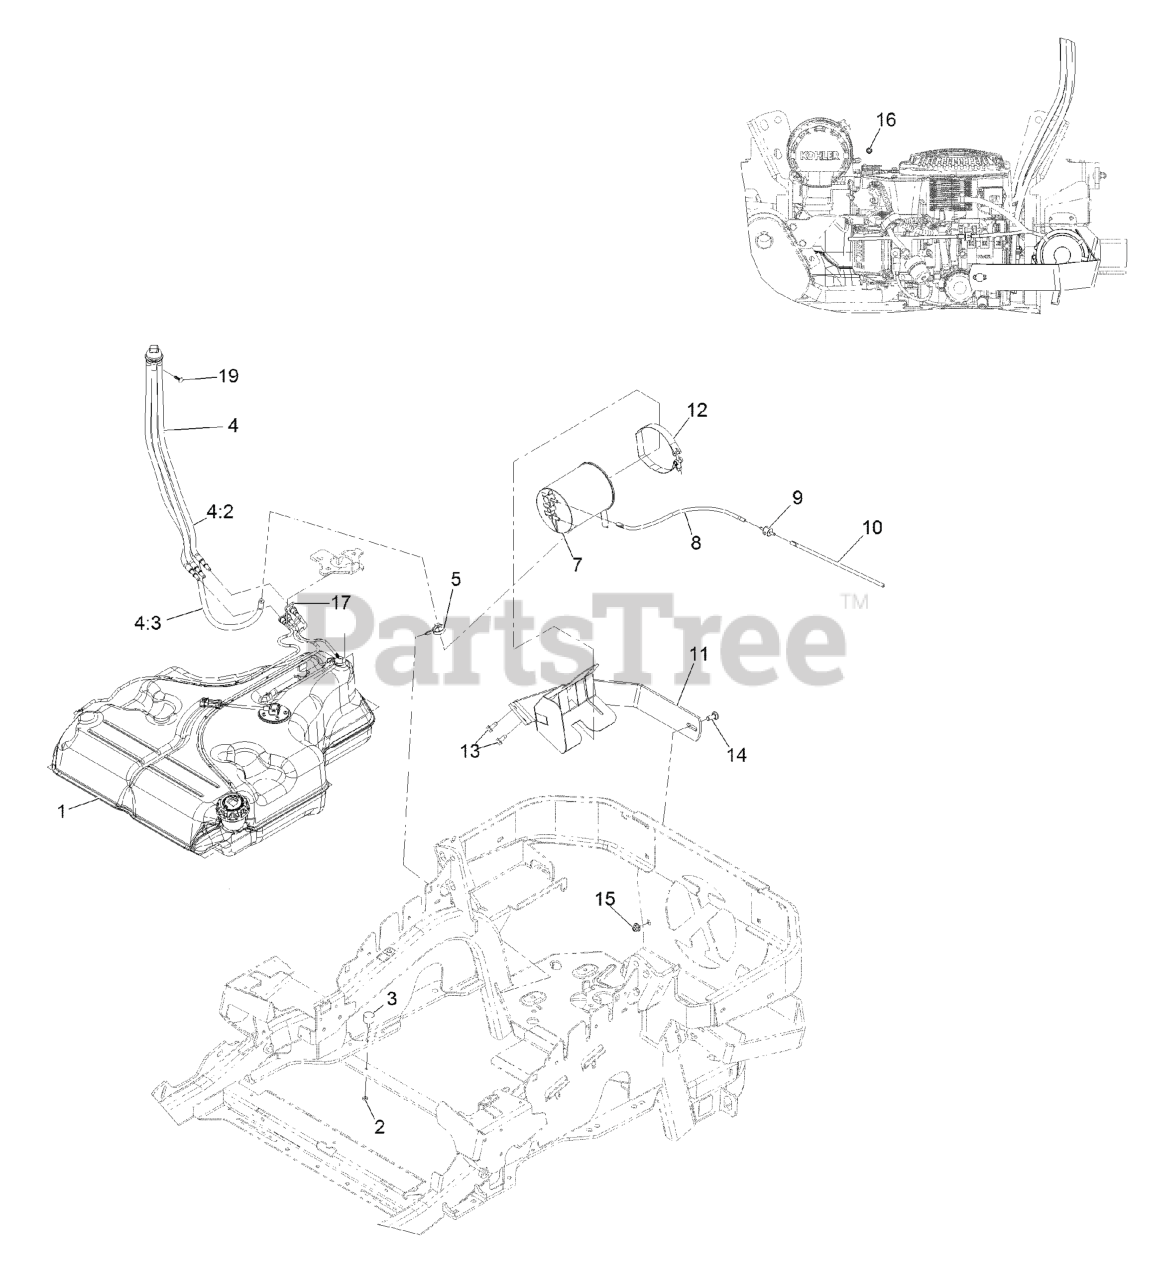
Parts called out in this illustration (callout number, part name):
1	FUEL TANK ASM
2	NUT-JAM
4	FUEL MANIFOLD VENT ASM
4:2	HOSE-FUEL
4:3	HOSE-FUEL
5	CLAMP-HOSE
7	CANISTER-CARBON, 1200CC
8	HOSE-VENT, FORMED
9	VALVE-CHECK, VACUUM
10	HOSE-VENT, FORMED
11	MOUNT-CANISTER
12	CLAMP, T-BOLT
13	Screw-HWH 5/16-18 X 3/4 Tf
14	SCREW-CARR
15	NUT-HF, NI
16	PLUG-PORT
17	RETAINER-LINE, VAPOR
19	PLUG-PLASTIC
